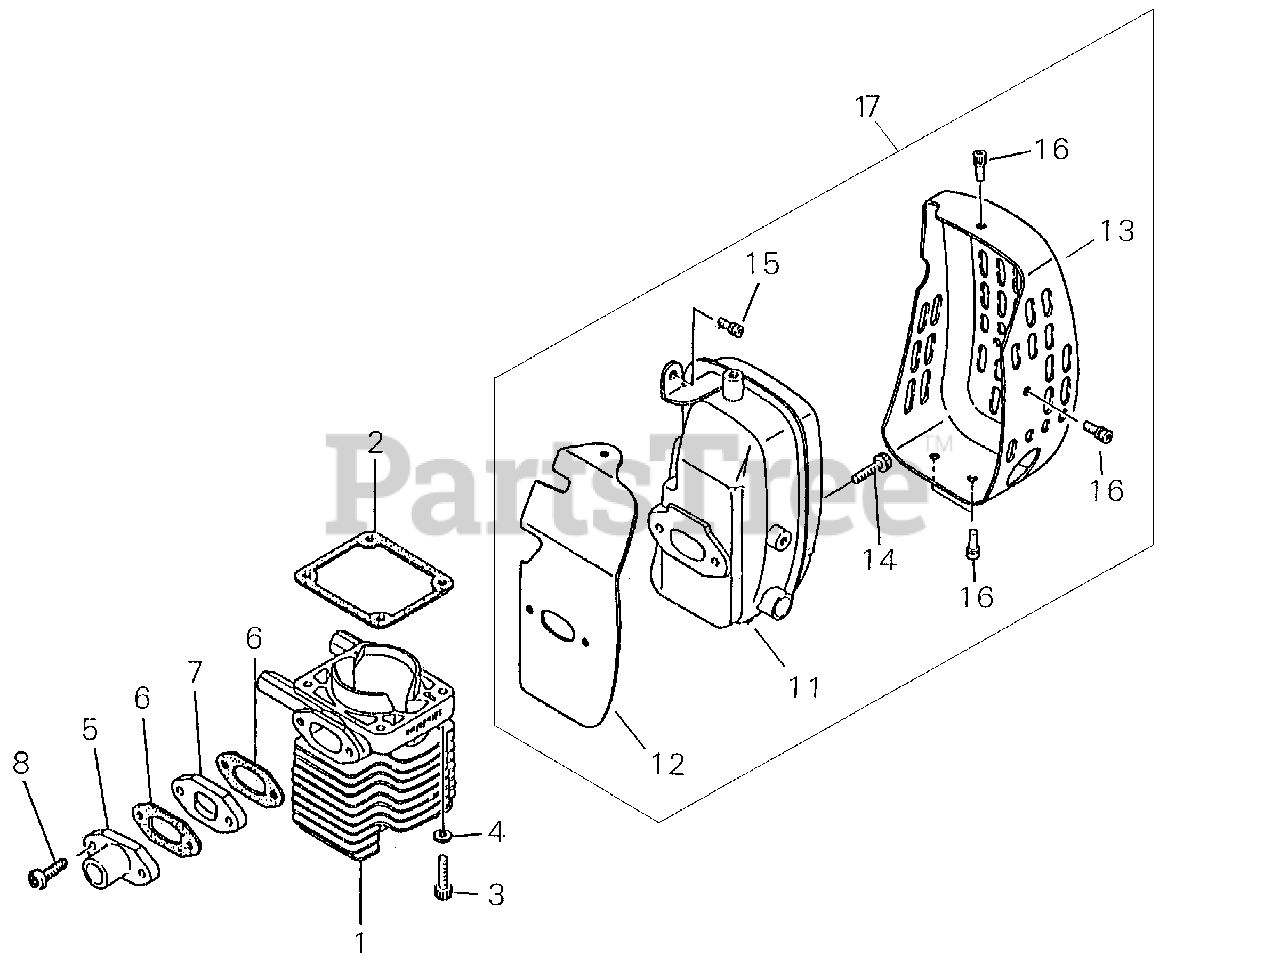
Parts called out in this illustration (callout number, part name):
1	CYLINDER
2	GASKET, CYLINDER
3	WASHER, SPRING 5
4	BOLT 5×25
5	PIPE, INTAKE
6	GASKET, INTAKE
7	INSULATOR
8	BOLT M5×20
11	MUFFLER
12	HEAT SHIELD, EXHAUST
13	COVER, MUFFLER
14	BOLT 6×25
15	BOLT M5×12
16	BOLT M5×10
17	MUFFLER ASSY
